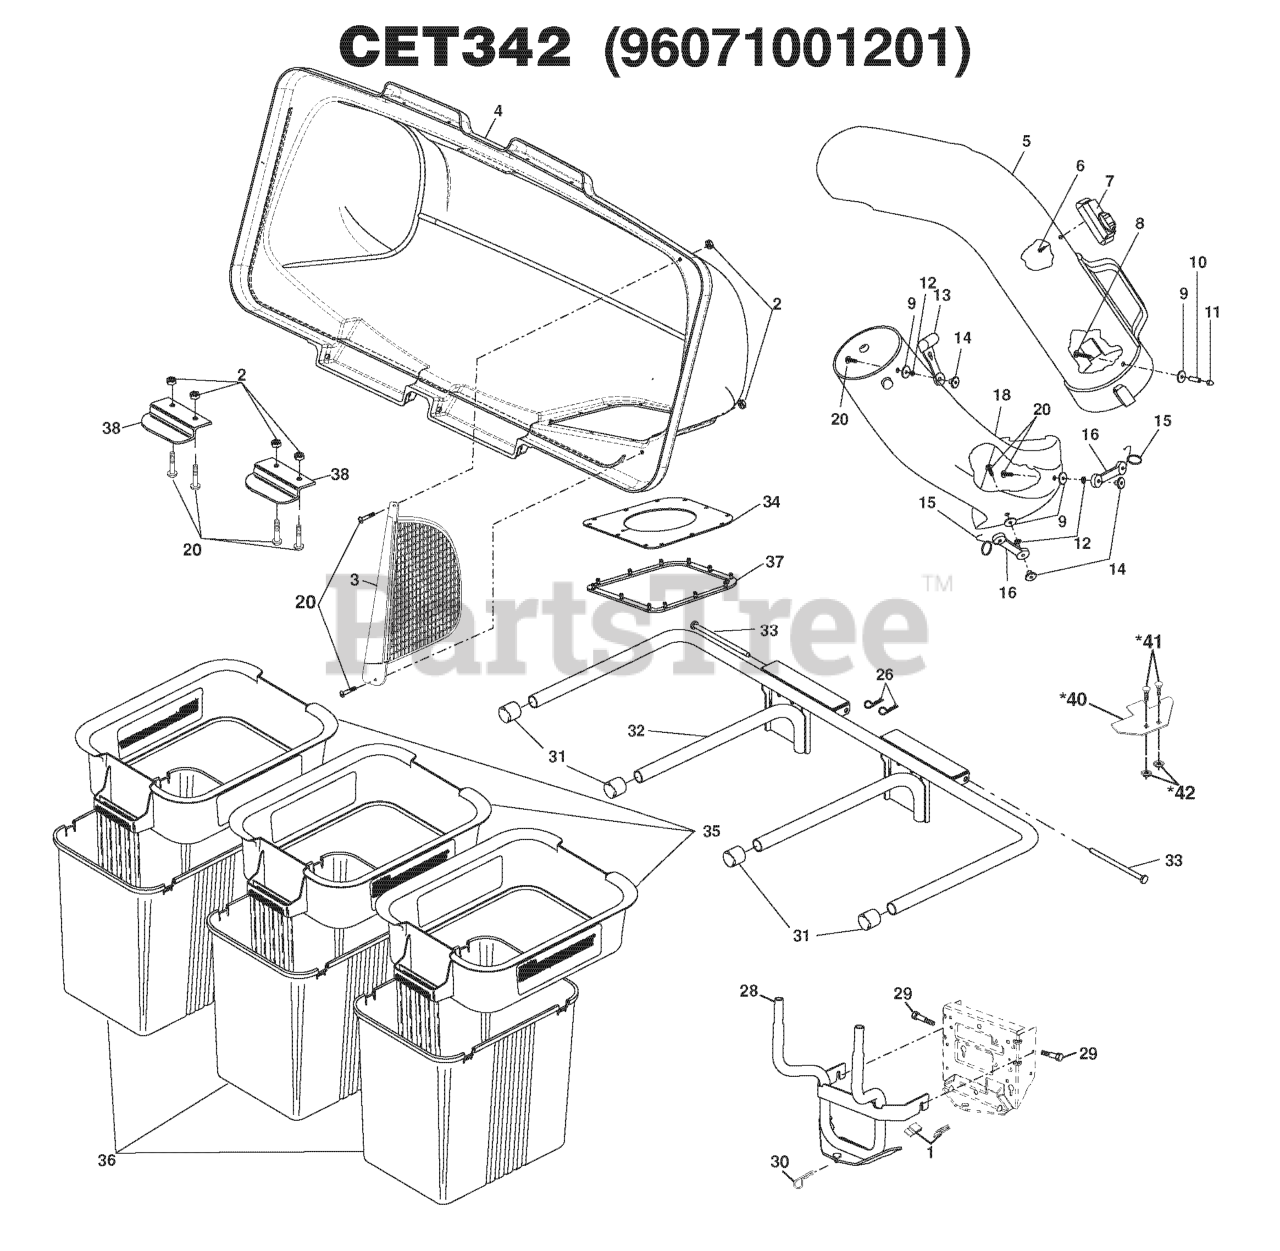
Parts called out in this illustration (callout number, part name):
1	ADAPTER.LT.3-BIN.QA.TEX
3	SCREEN.COVER.BAGGER
4	COVER.ASM.3BIN.GENERIC.
5	CHUTE.UPPER.42"
7	INDICATOR ASM BAG
8	SCREW
9	RP STEEL WASHER
11	NUT
12	LOCKWASHER #10
13	LATCH.HOOD.
14	WELDNUT
15	HOOK LATCH
16	RUBBER LATCH
18	LOWER CHUTE FOR 42" BAGGER
26	RETAINER-SPRNG RB
28	BRACKET.BAGGER.3-BIN.BLACK
29	BOLT.SHOULDER
30	SPRING.RETAINER.YELLOW.ZINC
31	PLUG, TUBING END
32	BAGGER.ASM.FRAME.3BIN.BLACK
33	BAGGER.HINGE.PIN
34	SEAL.BAGGER.TOP.3-BIN.BLK
35	CONTAINER TOP
36	CONTAINER BOTTOM
37	GASKET.COVER.BAGGER
38	LATCH CER38
